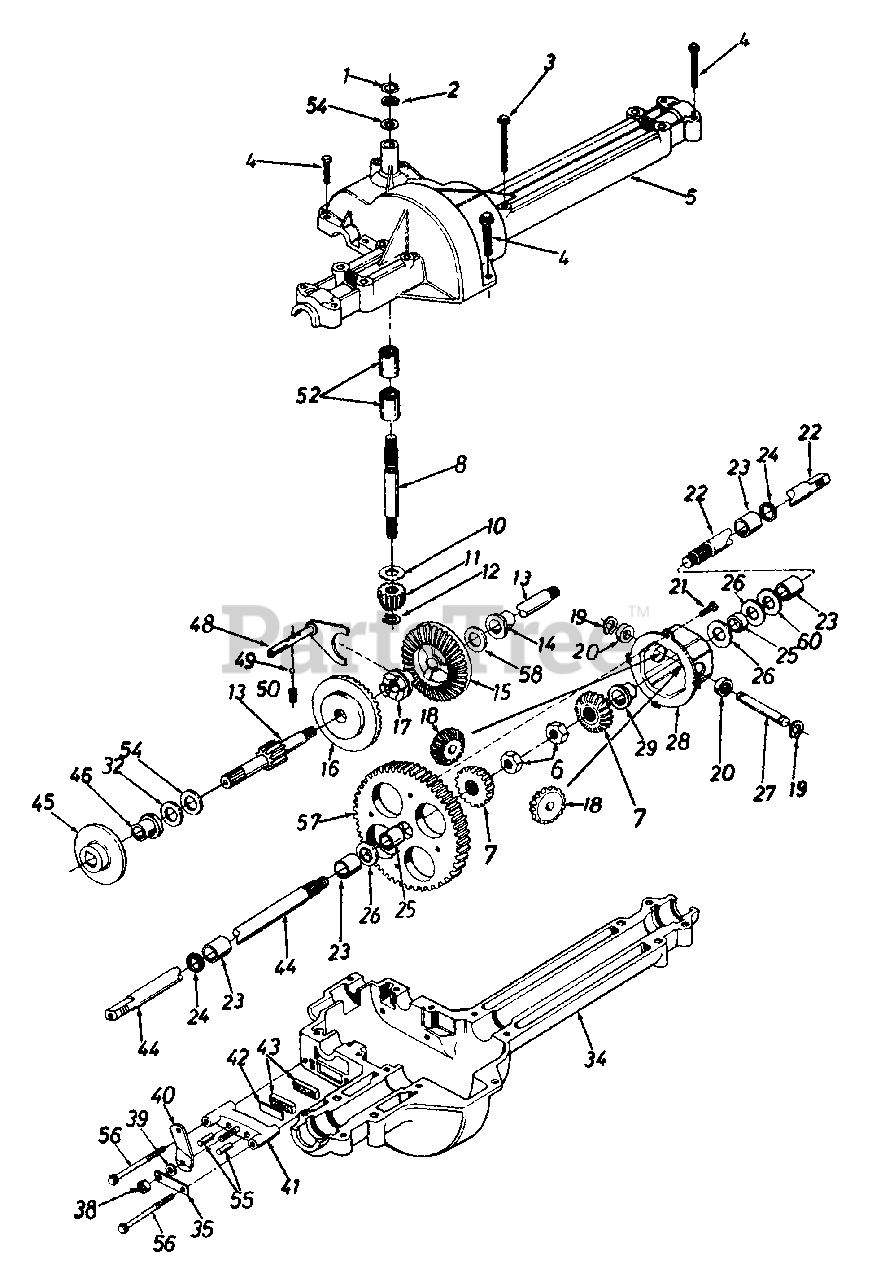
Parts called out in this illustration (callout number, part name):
2	Retaining - Ring
3	Hex Bolt 1/4-20 x 1.75" Lg.
4	Hex Tap Scr. 1/4-20 x 1.25" Lg.
5	Upper Housing
10	Thrust Washer 5/8" I.D. x 1.25" O.D.
11	Pinion Input 14T
12	Retaining Ring
13	Drive Shaft - L.H. Brake
14	Flange Brg. 5/8" I.D. x 3/4" Lg.
15	Bevel Gear 42T Small I.D.
16	Bevel Gear 42T Large I.D.
17	Clutch Collar
18	Miter Gear 15T (H.D.)
19	Retaining Ring
20	Thrust Bearing
21	Pan Head Scr. 1/4-20 x .50" Lg. w/Patch
22	Axle R.H. Ass'y.
23	Sleeve Bearing 3/4" I.D. x 1.0" Lg.
24	Oil Seal 3/4" I.D.
26	Fl-Wash. .760" I.D. x 1.5" O.D.
28	Differential Can Ass'y.
32	Washer
32	Thrust Wash. 5/8" I.D. x 1" O.D. x .025" Thk.
34	Lower Housing
35	Anti-Rotation Brkt.
38	Hex Nut 5/16-24 Thd.
39	Fl-Wash. .344" I.D. x .875" O.D.
40	Actuating Arm
41	Brake Yoke
42	Puck Plate
43	Brake Puck
44	Axle L.H. Ass'y.
46	Flange Bearing 5/8" I.D. x 15/16" Lg.
48	Shift Fork Ass'y.
49	Ball Detent .250" Dia.
50	Spring Detent
52	Needle Brg. 5/8" I.D. x 1/2" Lg.
54	Fl-Wash. 5/8" I.D. x 1" O.D. x .020 Thk.
55	Actuating Pin 5/16" Dia.
56	Hex Wash Hd. Self-Tap Scr. 1/4-20 Thd.
57	Differential Gear 58T
58	Fl-Wash. 5/8" I.D. x 1" O.D. x .020 Thk.
60	Fl-Wash. .76" I.D. x 1.5" O.D. x .010" Thk.
